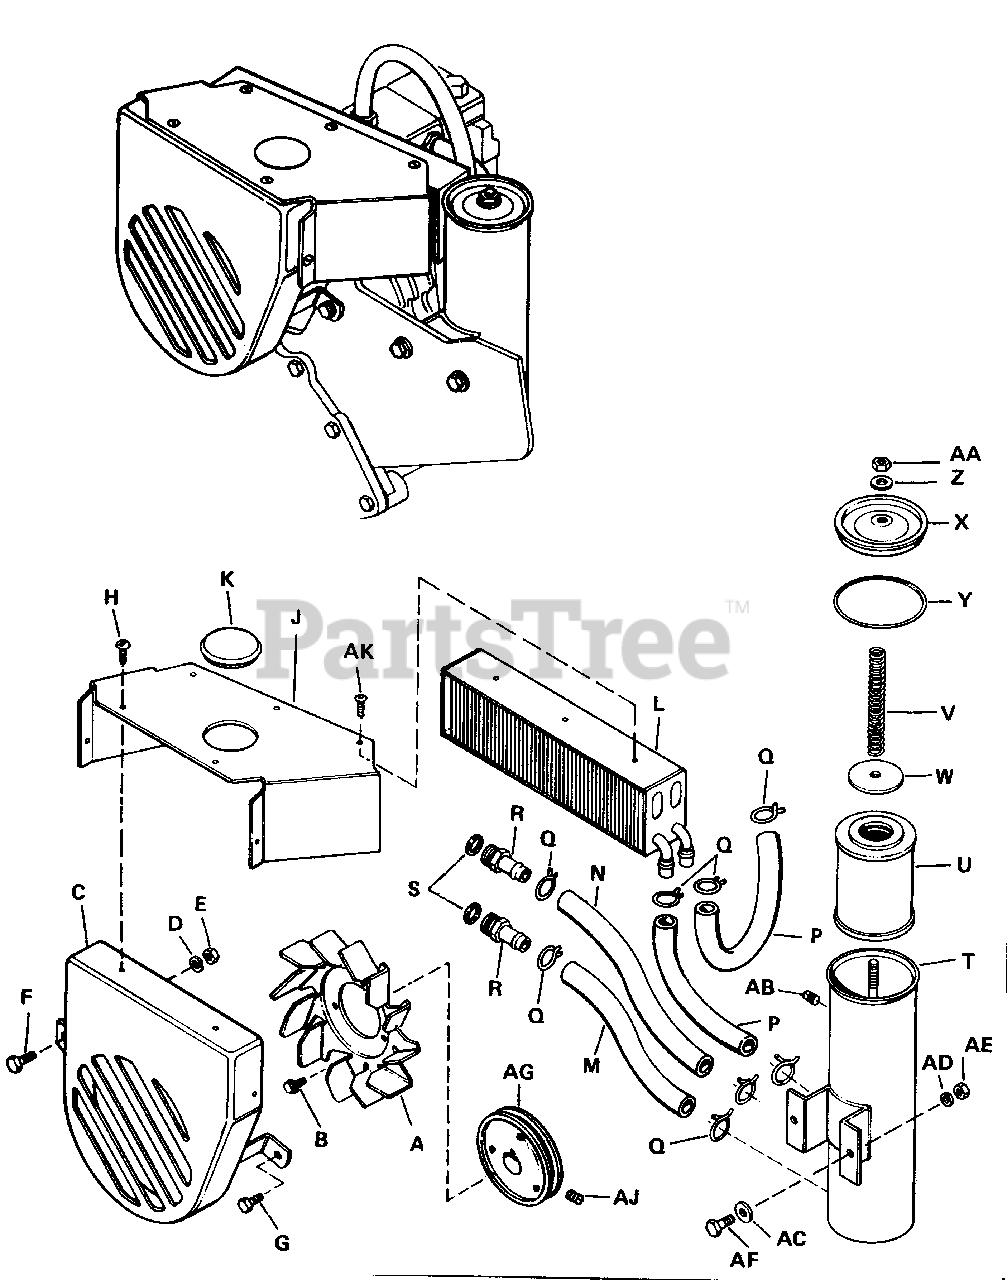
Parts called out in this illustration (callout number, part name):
B	Hex. Screw, Washer Hd.
C	Fan Shroud Assembly
D	Lock Washer, 5/16"
E	Full Hex. Nut 5/16"-18
F	Hex. Capscrew 5/16-18 x 3/4"
G	Hex. Screw, Thd.
H	Tapscrew, Round hd. slot 3/8"
J	Cooler Deflector
L	Oil Cooler
M	Hydraulic Hose
N	Hydraulic Hose
P	Hydraulic Hose
Q	Hose Clamp
R	Beaded Insert
T	Reservoir Assembly
U	Filter Element
X	Reservoir Cover
Z	Nylon Washer
AA	Elastic Stop Nut 5/16"-18
AB	Pipe Plug 1/4"
AC	Plain Washer, 5/16"
AD	Lock Washer, 5/16"
AE	Full Hex. Nut, 5/16-18"
AF	Hex. Capscrew, 5/16-18 x 3/4"
AG	Driven Pulley
AJ	Cup Pt. Socket Hd. Set Screw, 5/16-18 x 5/16"
AK	Rd. Hd. Mach Screw, No. 10-32 x 1/2" lg.
